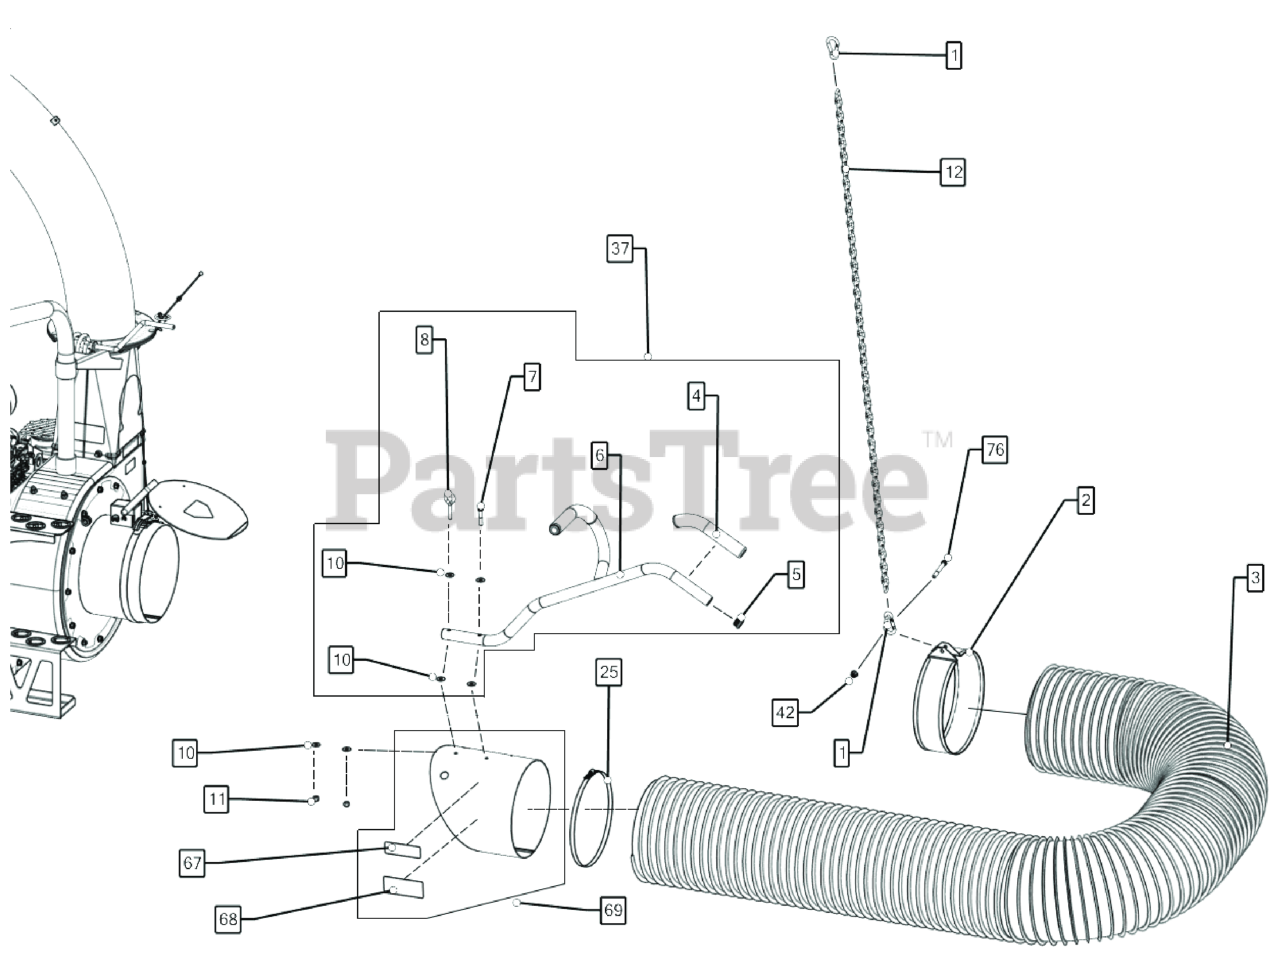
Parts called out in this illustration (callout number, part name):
1	HOOK, SNAP SAFETY 5/16" ZP
2	BAND HOSE BOOM 12" FORMED
3	HOSE INTAKE 12"X 10' (SEE ACCESSORY PRICE LIST ITEM 791034-S)
4	GRIP 1-1/4" ID X 9.5" LONG
5	PLUG TUBE INSERT 1.25" O.D.
6	HANDLE NOZZLE DEBRIS LOADER
7	SCREWCAP 3/8"-16X2" HCS ZP
8	BOLT EYE G-2 3/8" X 2"
10	WASHER 3/8"FC7/16"X1"X5/64"
11	NUT LOCK 3/8"-16 HEX
12	CHAIN 73 LINKS DL
25	SEE: 790150-01
37	SEE: 791116-S
42	NUT-HEX-NYLK, FLG .375"-16 ZP
67	LABEL WARNING HOSE TRAY QL23
68	LABEL WARNING ENGINE OVERHEAT
69	NOZZLE INTAKE 12" SERVICE
76	SCREWCAP 3/8"-16X3" HCS ZP
